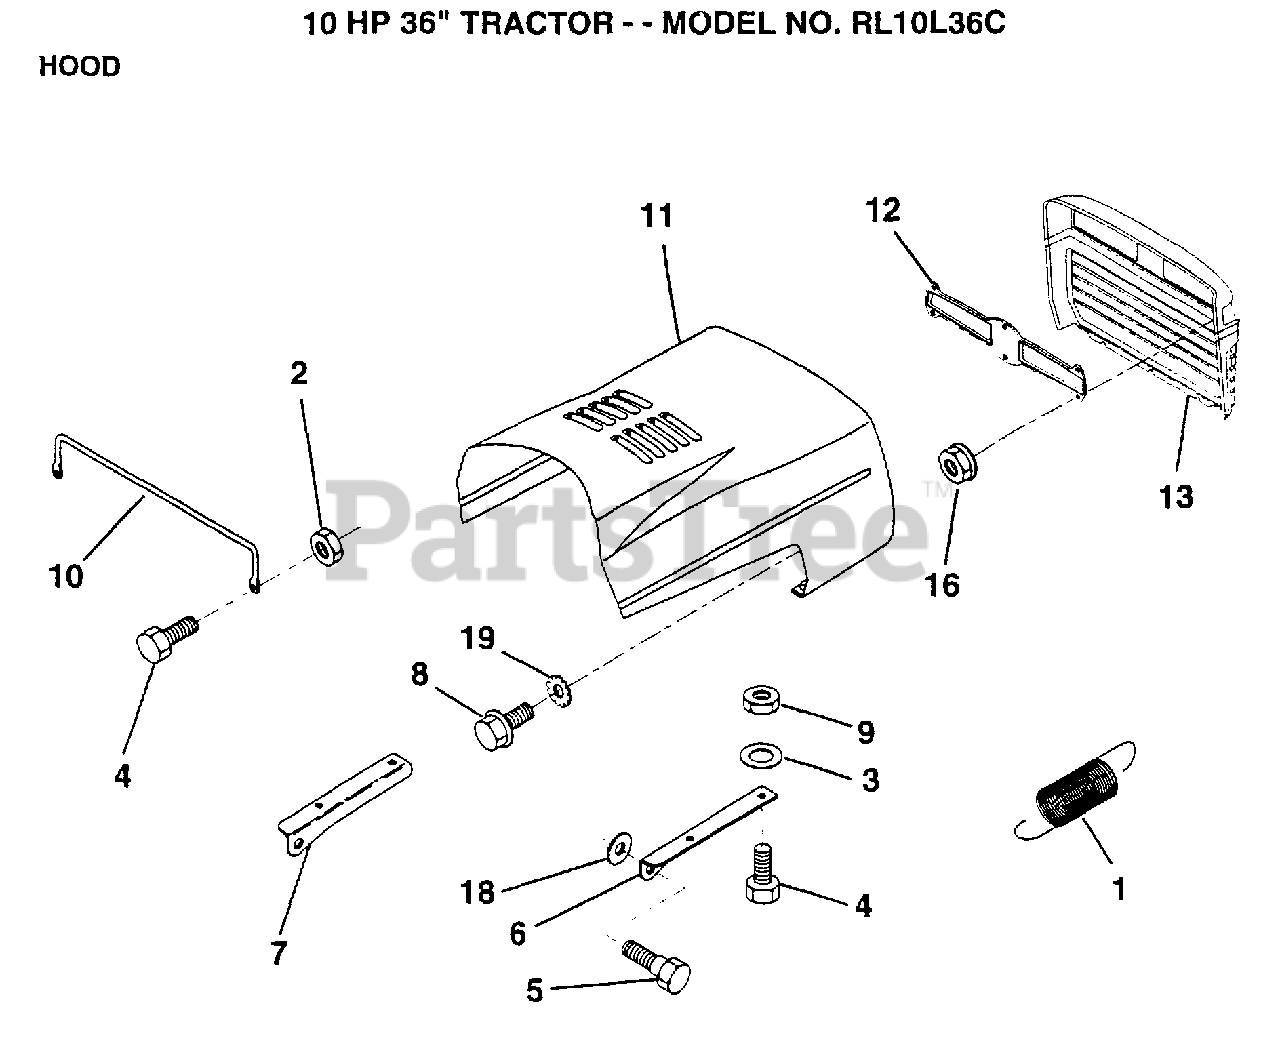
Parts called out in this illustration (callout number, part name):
1	EXT SPRING
2	NUT
3	WASHER
6	BRKT HOOD RH
7	BRKT HOOD LH
9	NUT
10	"BRACE,HOOD"
11	HOOD
13	GRILL (BLACK)
16	NUT
18	WASHER
19	LOCKWASHER GT
